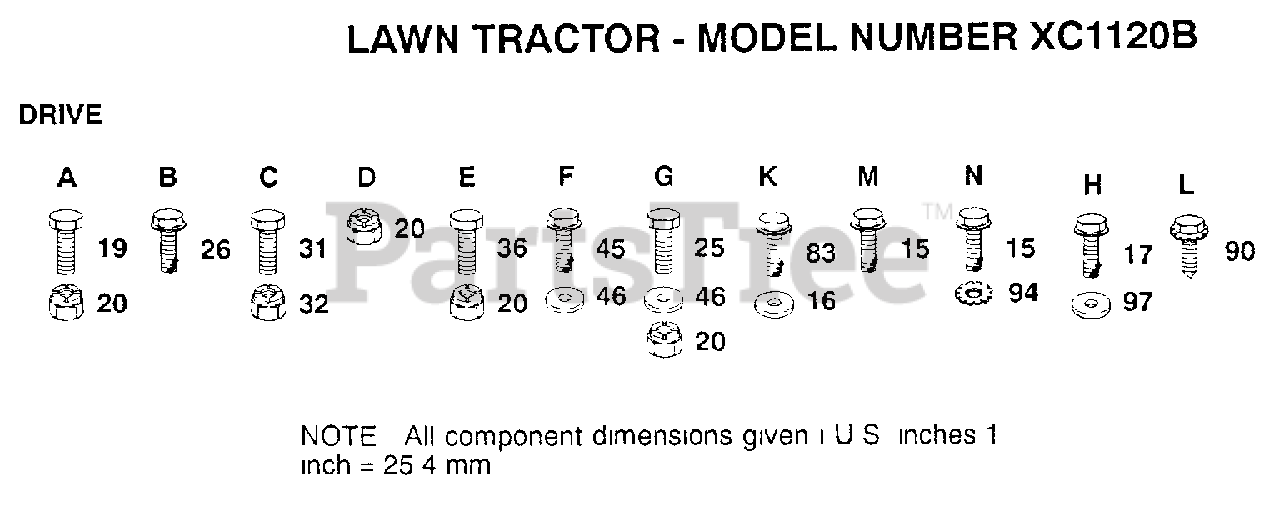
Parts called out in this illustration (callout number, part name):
15	SCREW
16	LOCKWASHER
17	"BOLT,HEX"
19	BOLT
25	BOLT
26	SCREW
31	BOLT
45	SCREW
46	WASHER
94	LOCKWASHER
97	WASHER T
